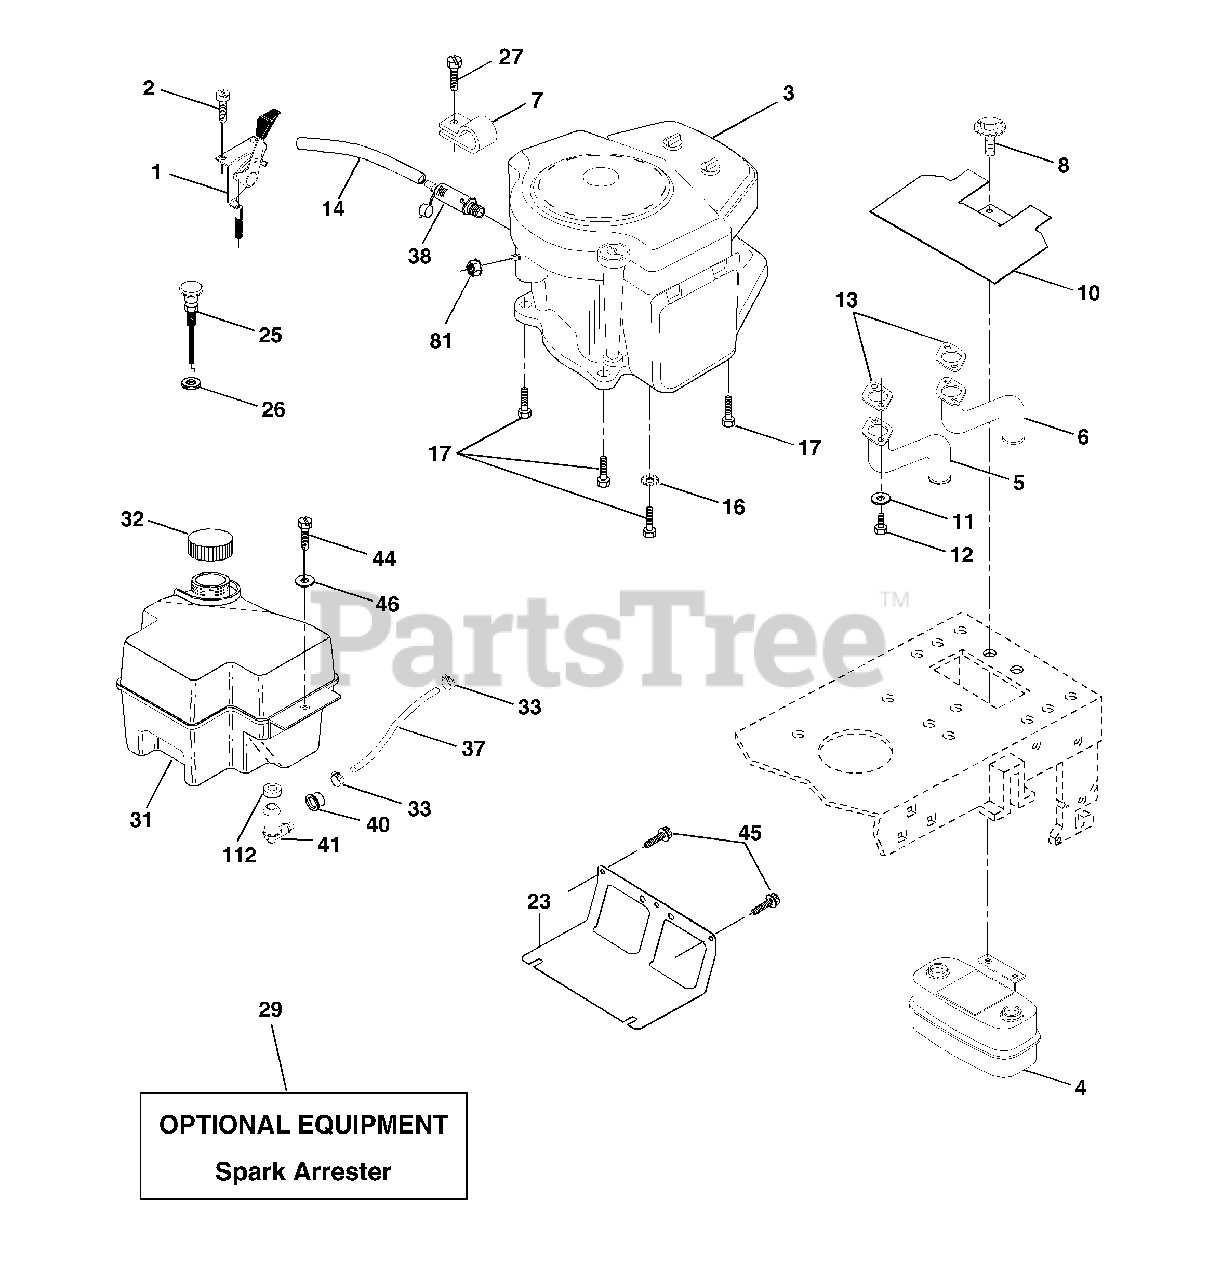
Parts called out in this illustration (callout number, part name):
1	Control Throt
2	Screw Hex Thd Cut 1/4-20x5/8 T
4	Muffler Exhaust
5	Exhaust Asm. Lh
6	Exhaust Asm. Rh
7	Clamp Tube Double Engine
8	Bolt 5/16-18unc x 3/4 w/sems
10	Heat Shield Lt
11	Washer Lock Hvy. Helical 1/4
12	Screw Hex Hd Cap 5/16-18 x 3/4
13	Gasket Muffler
14	Tube Drain Oil Easy
16	Washer Lock Ext Tooth 3/8
17	Screw 3/8-16x1-1/2
23	Shield BRN/DBR Guard
25	Control Choke
26	Nut Keps 3/8-24 Unf
27	Screw
29	Arrestor Spark
31	Tank Fuel
32	Cap Fuel
33	Clamp Hose Blk
37	Line Fuel
38	Plug Drain Oil Easy
40	Bushing Snap Nyl Black
41	Stem Tank Fuel
44	Screw Hexwsh Thdrol 1/4-20 x 3/4
45	Screw Hex wsh Thdrol 3/8-16 x 3/4
46	Washer 9/32 x 7/8 x 16 Ga.
81	Nut Keps Hex 1/4-20 Unc
112	Bushing
